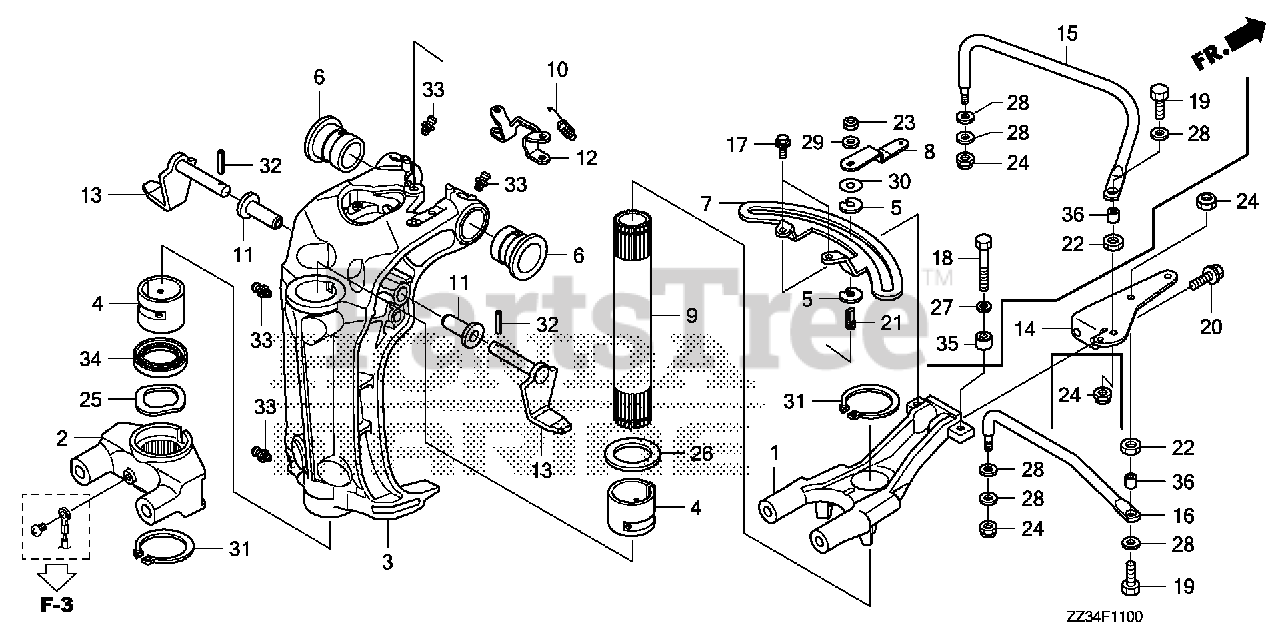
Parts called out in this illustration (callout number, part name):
1	FRAME, MOUNT
2	HOUSING, CENTER MOUNTING (LOWER) *NH282MU* (OYSTER SILVER METALLIC-U)
3	CASE, SWIVEL *NH282MU* (OYSTER SILVER METALLIC-U)
4	LINER, SWIVEL CASE
6	BUSH, SWIVEL CASE
9	SHAFT, SWIVEL
10	SPRING, TILT LEVER
11	BUSH, TILT ARM
12	BRACKET, TILTING
13	STOPPER, TILT
14	PLATE, STEERING
16	ROD, STEERING
19	BOLT (3/8-24UNF)
20	BOLT, FLANGE (10X25)
22	NUT (3/8-24UNF)
24	NUT, SELF-LOCK (3/8-24UNF)
25	WASHER, WAVE (40MM)
26	WASHER, THRUST (34MM)
28	WASHER (10MM)
31	CIRCLIP (OUTER) (39MM)
32	PIN, SPRING (2.5X20)
33	NIPPLE, GREASE
34	OIL SEAL (39.5X52X6) (ARAI)
36	COLLAR, STEERING ROD
